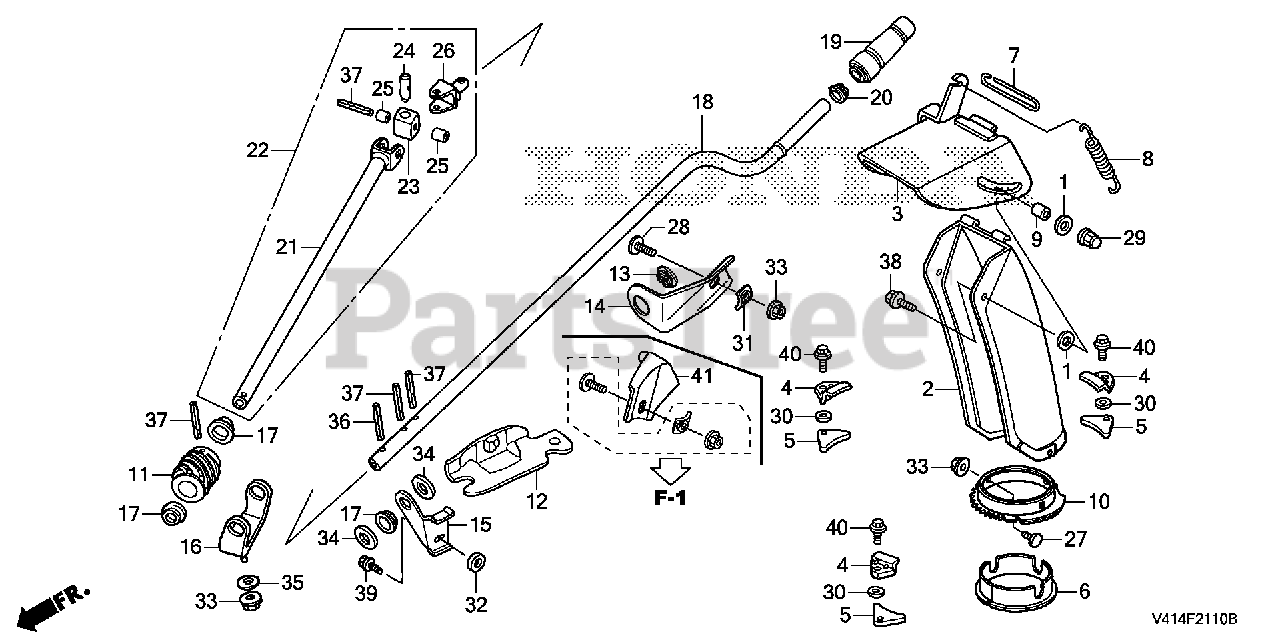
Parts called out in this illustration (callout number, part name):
1	WASHER, ACCELERATOR PEDAL
2	CHUTE
3	GUIDE, CHUTE (COO)
4	PLATE, CHUTE SETTING
5	PLATE, CHUTE SETTING (B)
6	BUSH, CHUTE
7	PIN, CHUTE GUIDE
8	SPRING, CHUTE
9	COLLAR, CHUTE GUIDE
10	GEAR, CHUTE
11	GEAR, CHUTE DRIVE
12	HOLDER, HANDLE BRACKET
13	BUSH, CHUTE HANDLE
15	BRACKET B, CHUTE HANDLE
16	STAY, DRIVE GEAR
17	BUSH, DRIVE GEAR
18	HANDLE, CHUTE (UPPER)
19	GRIP, CHUTE HANDLE
20	BUSH A, CHUTE HANDLE
22	HANDLE, CHUTE (LOWER)
23	PIECE, JOINT
24	PIN A, JOINT
25	PIN B, JOINT
27	BOLT, SPECIAL (8X15)
29	NUT, CAP (6MM)
30	WASHER, CHUTE SETTING
33	NUT, FLANGE (8MM)
34	WASHER, PLAIN (16MM)
35	WASHER, PLAIN (8MM)
36	PIN, SPRING (4X22)
37	PIN, SPRING (4X28)
38	BOLT, FLANGE (6X14)
39	BOLT, FLANGE (6X12)
40	BOLT, FLANGE (8X16)
41	BRACKET A, CHUTE HANDLE
